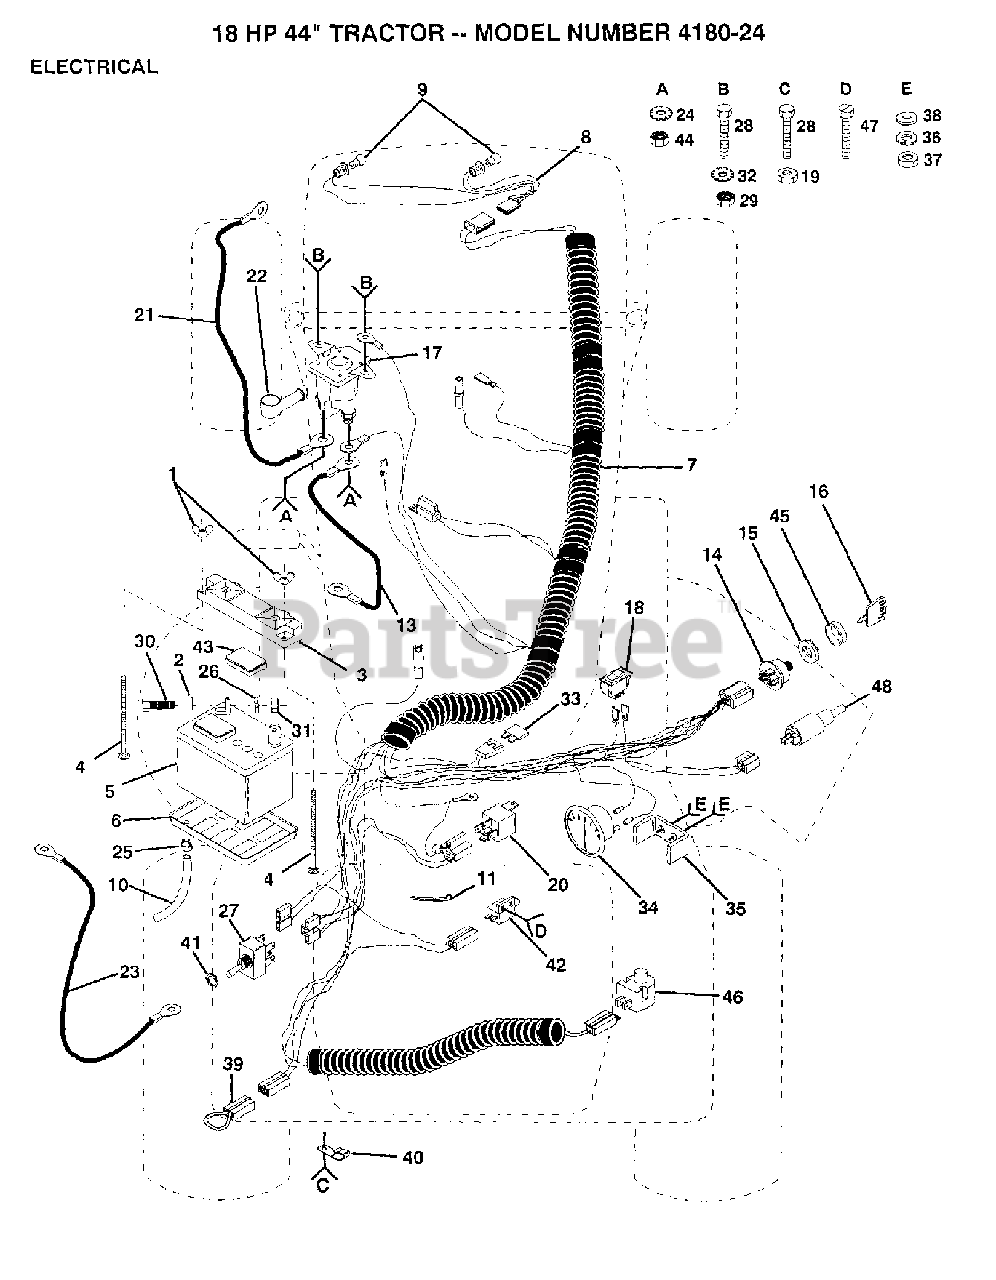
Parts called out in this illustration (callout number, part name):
1	WING NUT
2	WASHER
5	BATTERY
6	TRAY.BATTERY
8	HARNESS LIGHT SOC
10	BATT DRAIN TUBE T
11	WIRE TIE
14	SWITCH YTV
15	NUT
16	KEY.MOLDED.GENERIC
17	SOLENOID KIT
18	SWITCH LT
19	NUT.CROWNLOCK.1/4
20	RELAY.ASSY.T
21	BATTERY CABLE
22	TERMINAL COVER
23	TIRE HEAVY DUTY
25	HOSE CLAMP T
26	LOCKWASHER
28	BOLT
29	NUT
30	BOLT.HEX.1/4.X.3/4.DICHROMATE
31	NUT
32	LOCKWASHER
33	FUSE *
34	AMMETER.ROUND.15 AMP
35	AMMETER BRACKET
38	WASHER
39	LOOP-WIRE YTV
41	HEX NUT T (1 2)
42	SWITCH-INTER. GT
43	CAP BATTERY NLA
44	NUT
45	COVER KEY IGNITIO
46	SWITCH SEAT
48	Poulan TBD
